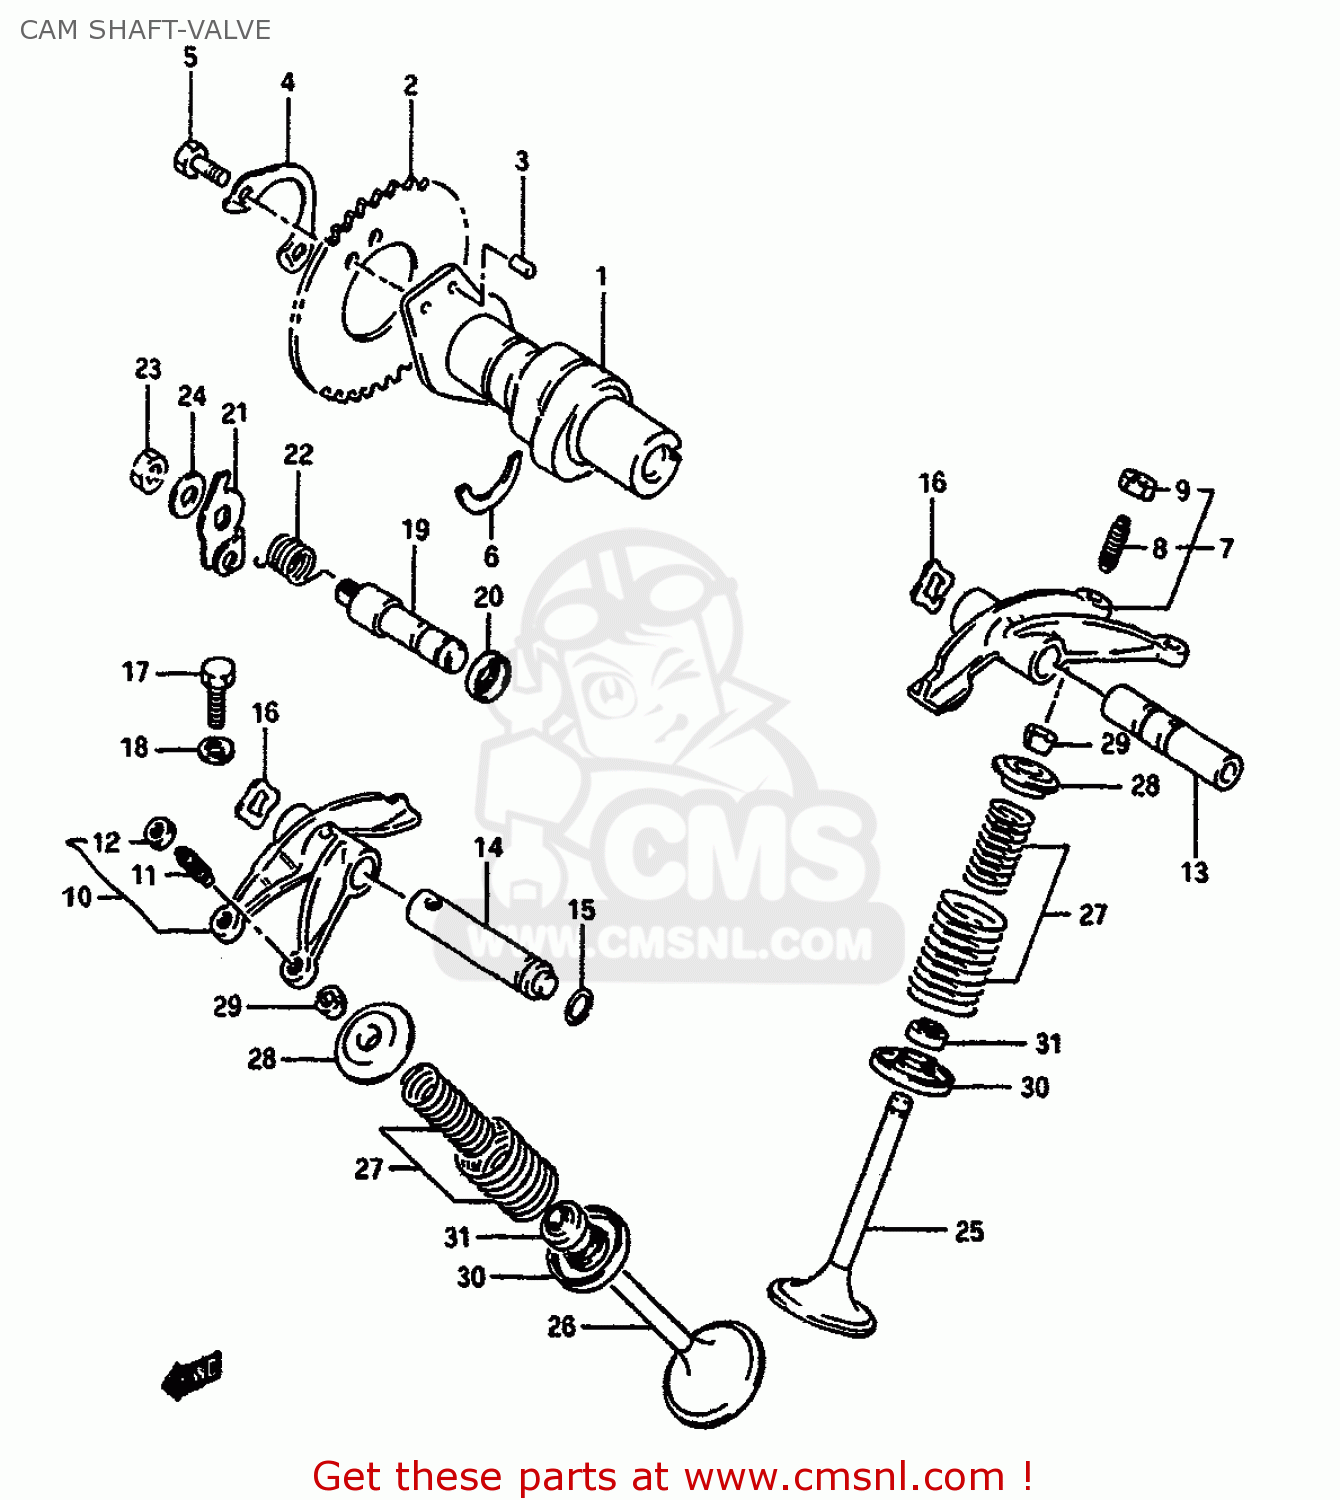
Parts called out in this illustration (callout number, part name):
1	CAMSHAFT
2	SPROCKET,CAMSHAFT(NT:42)
3	PIN
4	WASHER,CAM CHAIN SPROCKET
5	BOLT(6X12.5)
6	C RING
7	ARM,VALVE ROCKER INTAKE
8	SCREW,TAPPET ADJUSTING
9	NUT,ADJUSTING SCREW
10	ARM,VALVE ROCKER EXHAUST
11	SCREW,TAPPET ADJUSTING
12	NUT,ADJUSTING SCREW
13	SHAFT,VALVE ROCKER ARM INTAKE
14	SHAFT,EXHAUST VALVE ROCKER ARM
15	O RING(D:1.9,ID:8.6)
16	WASHER
17	BOLT 6X30
18	GASKET(5.8X13X1.2) (NAS)
19	SHAFT,DECOMPRESSION
20	SEAL,OIL(10X17X6)
21	LEVER,DECOMP SHAFT
22	SPRING,DECOMPRESSION SHAFT LEVER
23	NUT 8MM
24	WASHER
25	VALVE,INTAKE
26	VALVE,EXHAUST
27	SPRING SET,VALVE
28	RETAINER,VALVE SPRING
29	COTTER VALVE
30	SEAT,VALVE SPRING
31	SEAL,OIL(7X14.4X9)
